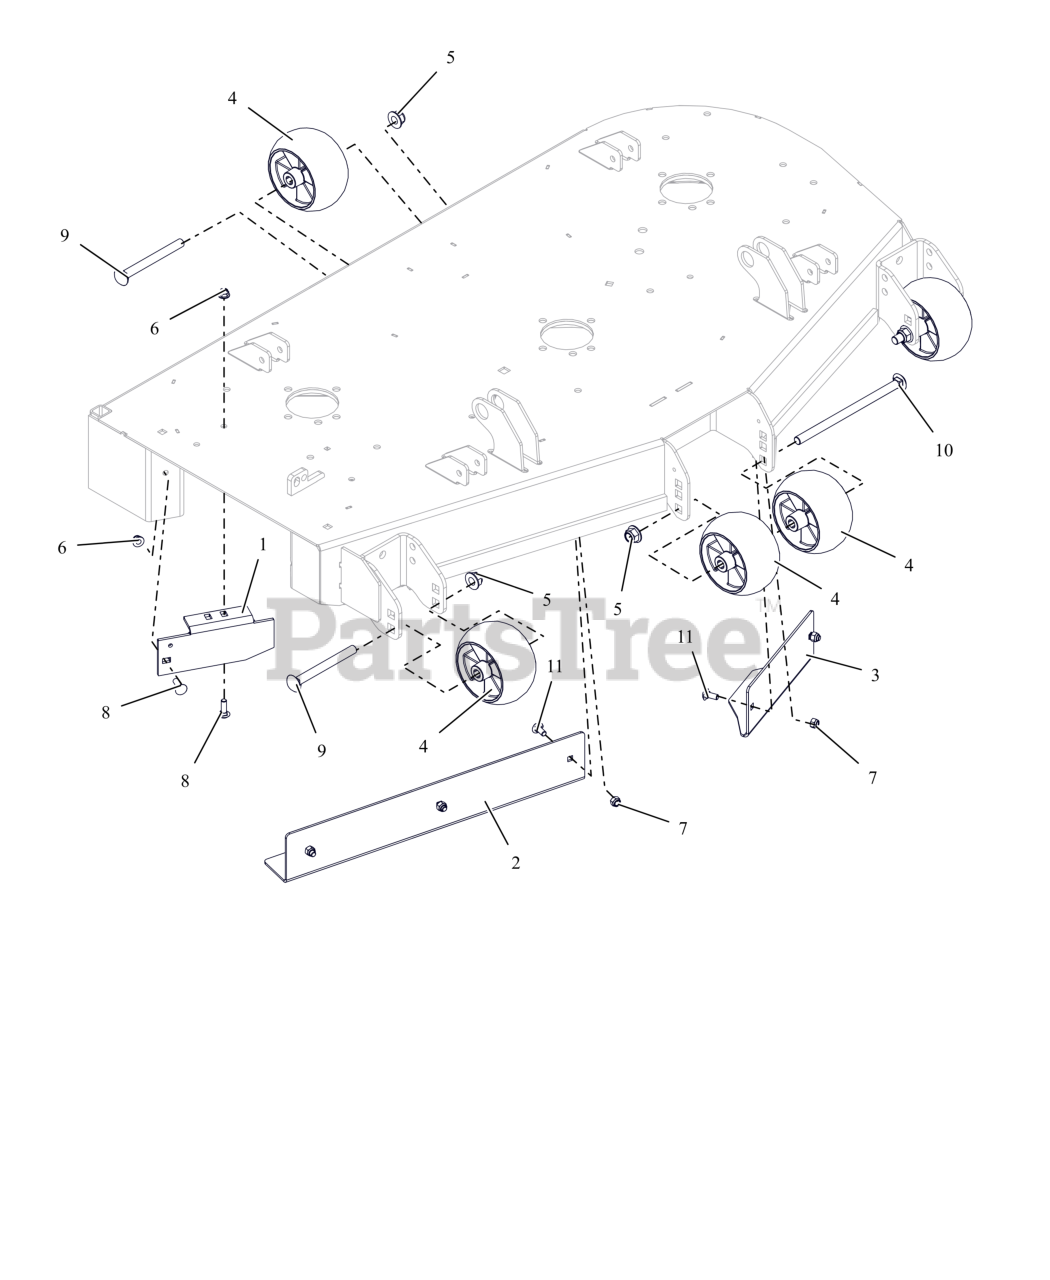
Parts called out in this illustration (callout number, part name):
1	44"-48" SIDE DISCH BAFFLE -RED
2	BAFFLE, 48" RH VACUUM (RED)
3	BAFFLE, 44/48" LH VACUUM (RED)
4	WHEEL, ANTI SCALP - 5X3 CTR W/RIBS
5	NUT,NYL-FLG .50-13 GF ZCC
6	NUT,NYL-FLG .31-18 GF ZCC
7	NUT,NYL .31-18 G5 ZCC
8	BLT,RHSN .31-18X1.00 G5 ZCC
9	BLT, RHSN .50-13X5.00 G5 ZCC
10	BTL,RHSN .500-13 X 8.5S G5 ZCC
11	BLT,RHSN .31-18X.75 G5 ZCC
